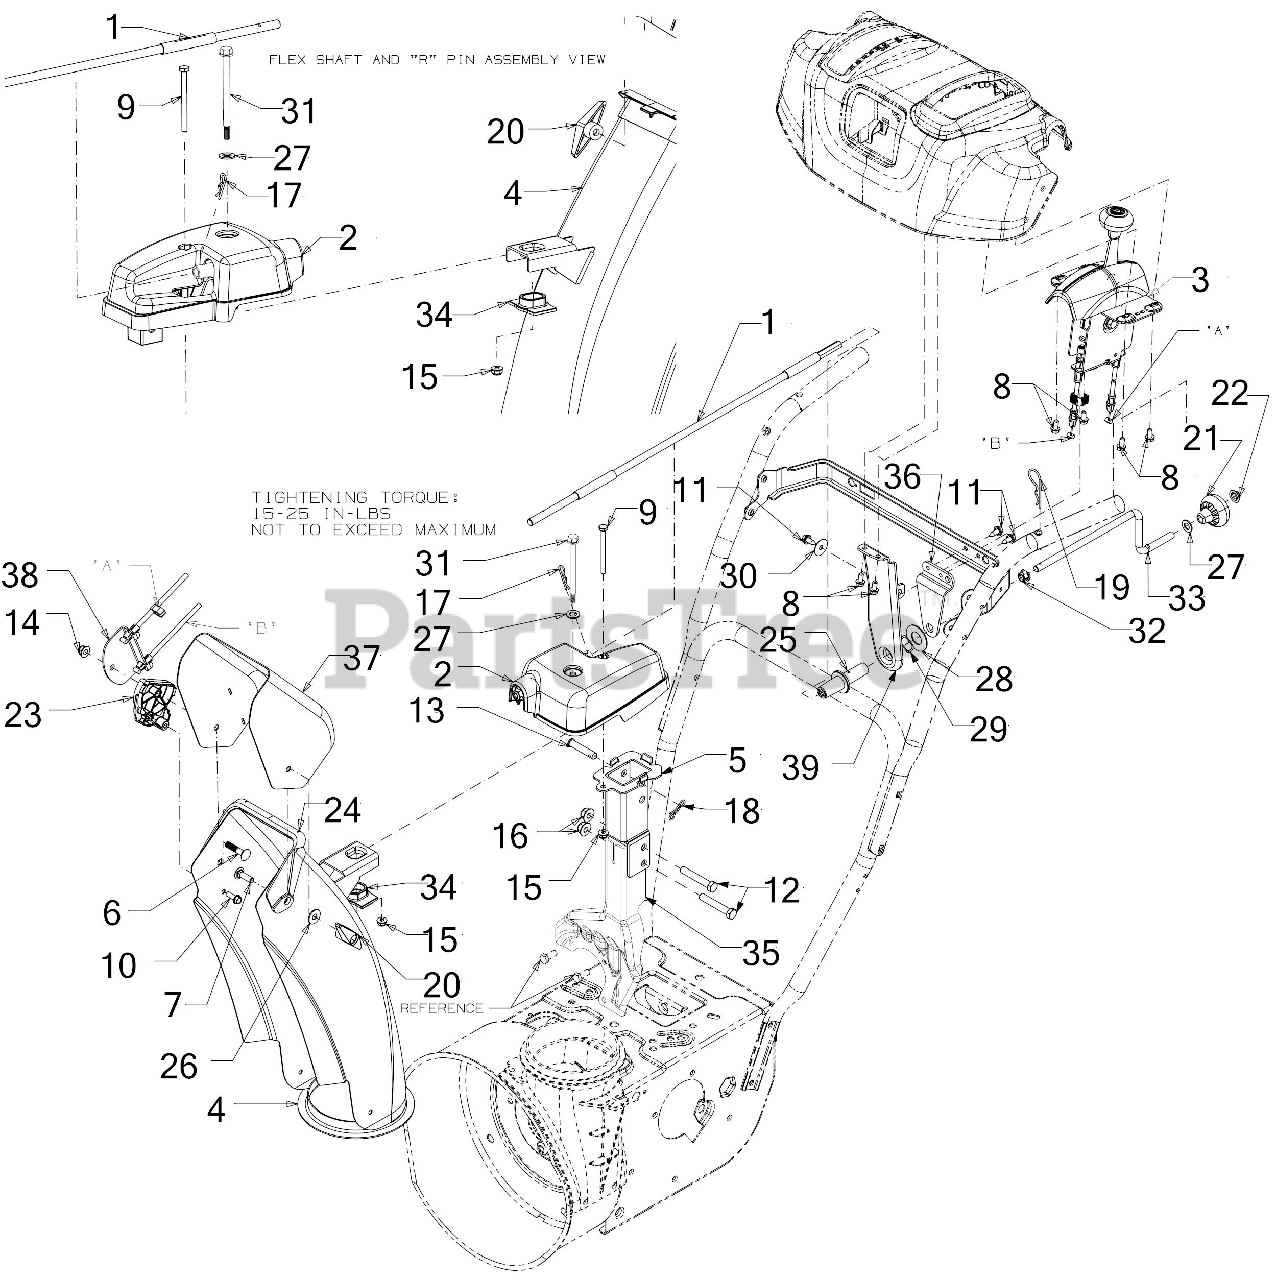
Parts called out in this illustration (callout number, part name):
1	CHUTE CONTROL SHAFT
2	WORM GEARBOX ASSEMBLY
3	2-WAY TALL CHUTE CONTROL ASSEMBLY
4	LOWER CHUTE
5	CHUTE EXTENSION MAST
6	CARRIAGE BOLT 5/16-18 x 1.50
7	CARRIAGE BOLT 5/16-18 x 1.00
8	HEX SCREW 1/4-15 x .50
9	SCREW 1/4-20 x 3.0 GR5
10	SCREW 1/4-15 x .750
11	SCREW 1/4-20X.625
12	SCREW 3/8-16 x 2.25 GR5
13	CLEVIS PIN 3/8 x 1.87
14	FLANGE LOCK NUT 5/16-18
15	FLANGE LOCK NUT
17	INTERNAL COTTER PIN
18	BOW TIE COTTER PIN 1/4-5/16
19	INTERNAL COTTER PIN
20	WING NUT KNOB
20	HEX NUT
20	STAR KNOB 5/16
21	SHIFT KNOB
22	PUSH NUT
23	CHUTE TILT GUIDE
24	UPPER CHUTE ADAPTER
25	CHUTE ROD COUPLER
26	FLAT WASHER
27	FLAT WASHER
28	FLAT WASHER
29	WAVE WASHER .785X1.00X.012
30	FLAT WASHER
31	SHOULDER SCREW
32	BUSHING .380 ID
34	HELICAL GEAR CHUTE ADAPTER
35	CHUTE SUPPORT BRACKET
36	ROD SUPPORT BRACKET
37	UPPER CHUTE STEEL
38	CABLE BRACKET GUIDE
39	CHUTE CONTROL BRACKET
